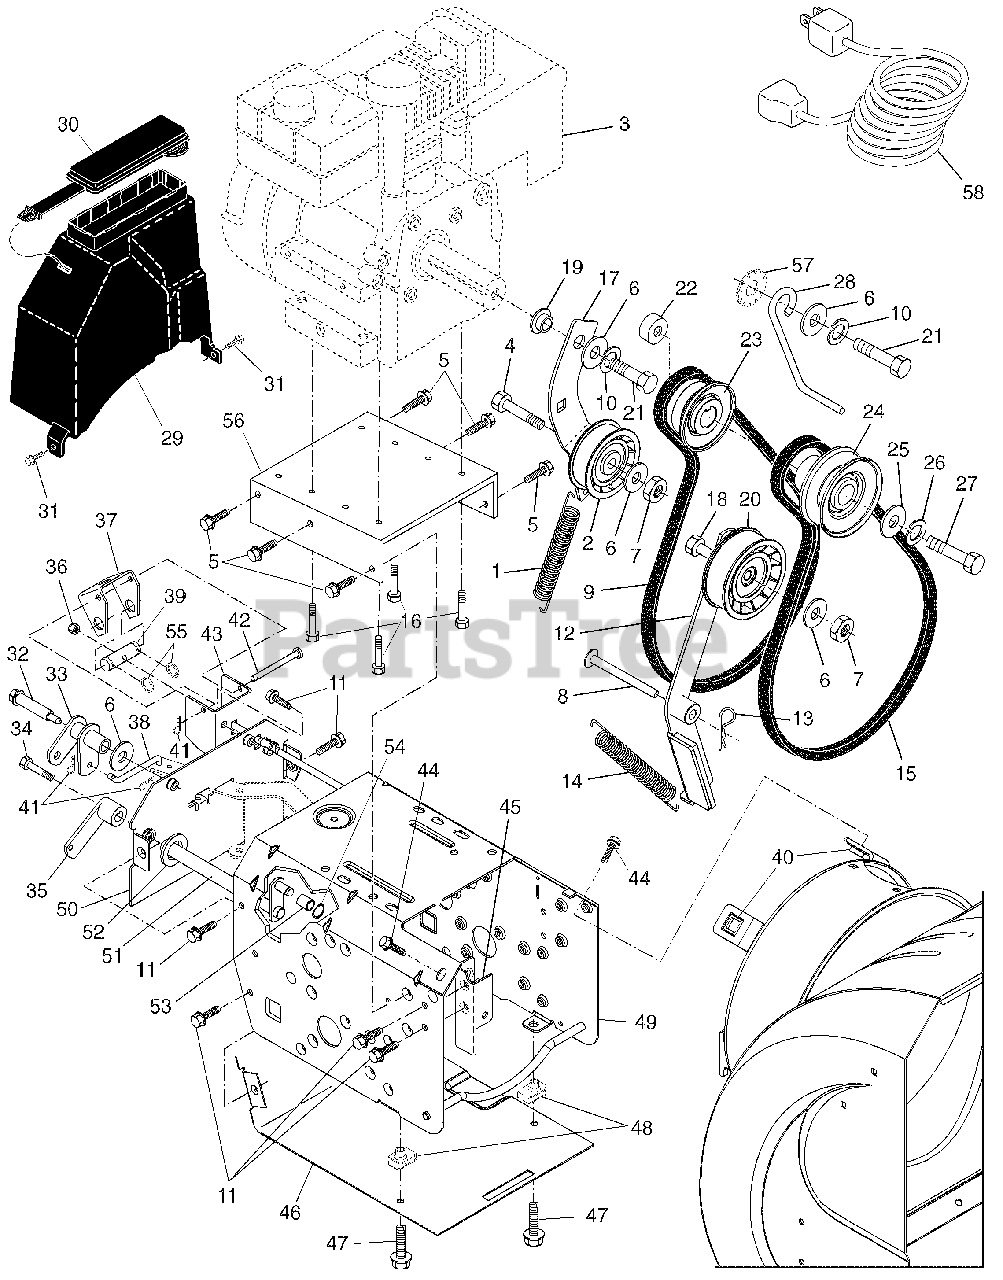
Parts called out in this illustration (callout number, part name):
1	Spring, Traction Idler
2	Pulley, Idler
4	Screw, Hex Head 5/16-18 x 1-1/4
5	Screw, Hex Head 5/16-18 x 3/4
6	Washer, Flat
7	Nut, Jam, Lock 5/16-18
8	Pin, Idler Pivot
9	V-Belt, Traction Drive
10	Washer, Lock 5/16
11	Screw, Hex Head 5/16-18 x 1/2
12	Impeller Idler Arm Assembly
13	Retainer, Hairpin
14	Spring, Brake
15	V-Belt, Impeller Drive
16	Screw, Hex Head 3/8-16 x 1-1/4
17	Arm, Idler
18	Screw, Hex Head 5/16-18 x 1-1/2
19	Bushing, Idler Pivot
20	Pulley, Idler
21	Screw, Hex Head 5/16-18 x 1
22	Spacer, Engine Pulley
23	Pulley, Engine, Traction Drive
24	Pulley, Engine, Impeller Drive
25	Washer, Flat 3/8
26	Washer, Lock, Helical 3/8
27	Screw, Hex Head 3/8-24 x 1-3/8
28	Guide, Belt
29	Belt Cover Assembly
30	Cover, Toolbox
31	Screw, Hex Head 1/4-20 x 1/2
32	Bolt, Shoulder 5/16-18
33	Bellcrank Shifter
34	Screw, Hex Head 1/4-28 x 3/4
35	Arm, Auger Control
36	Nut, Lock 5/16-18
38	Link, Speed Control
39	Trunnion, Pivot Bracket
40	Nut, Cage 3/8-16
41	Hairpin, Cotter 3/32 x 1/2
42	Pin, Pivot Bracket
43	Bracket, Bellcrank
44	Screw, Hex Head
45	Pivot Bracket, Impeller Idler Arm
46	Pan, Frame Bottom
47	Screw, Hex Head 5/16-18 x 3/4
48	Nut, Speed 5/16-18
49	Frame Assembly
50	Plate, Frame End
51	Shaft, Auger Control
52	Washer, Hardened
54	Ring, Crescent
56	Plate, Enging Mounting
57	Washer, Lock, External Tooth 5/16
58	Power Cord
